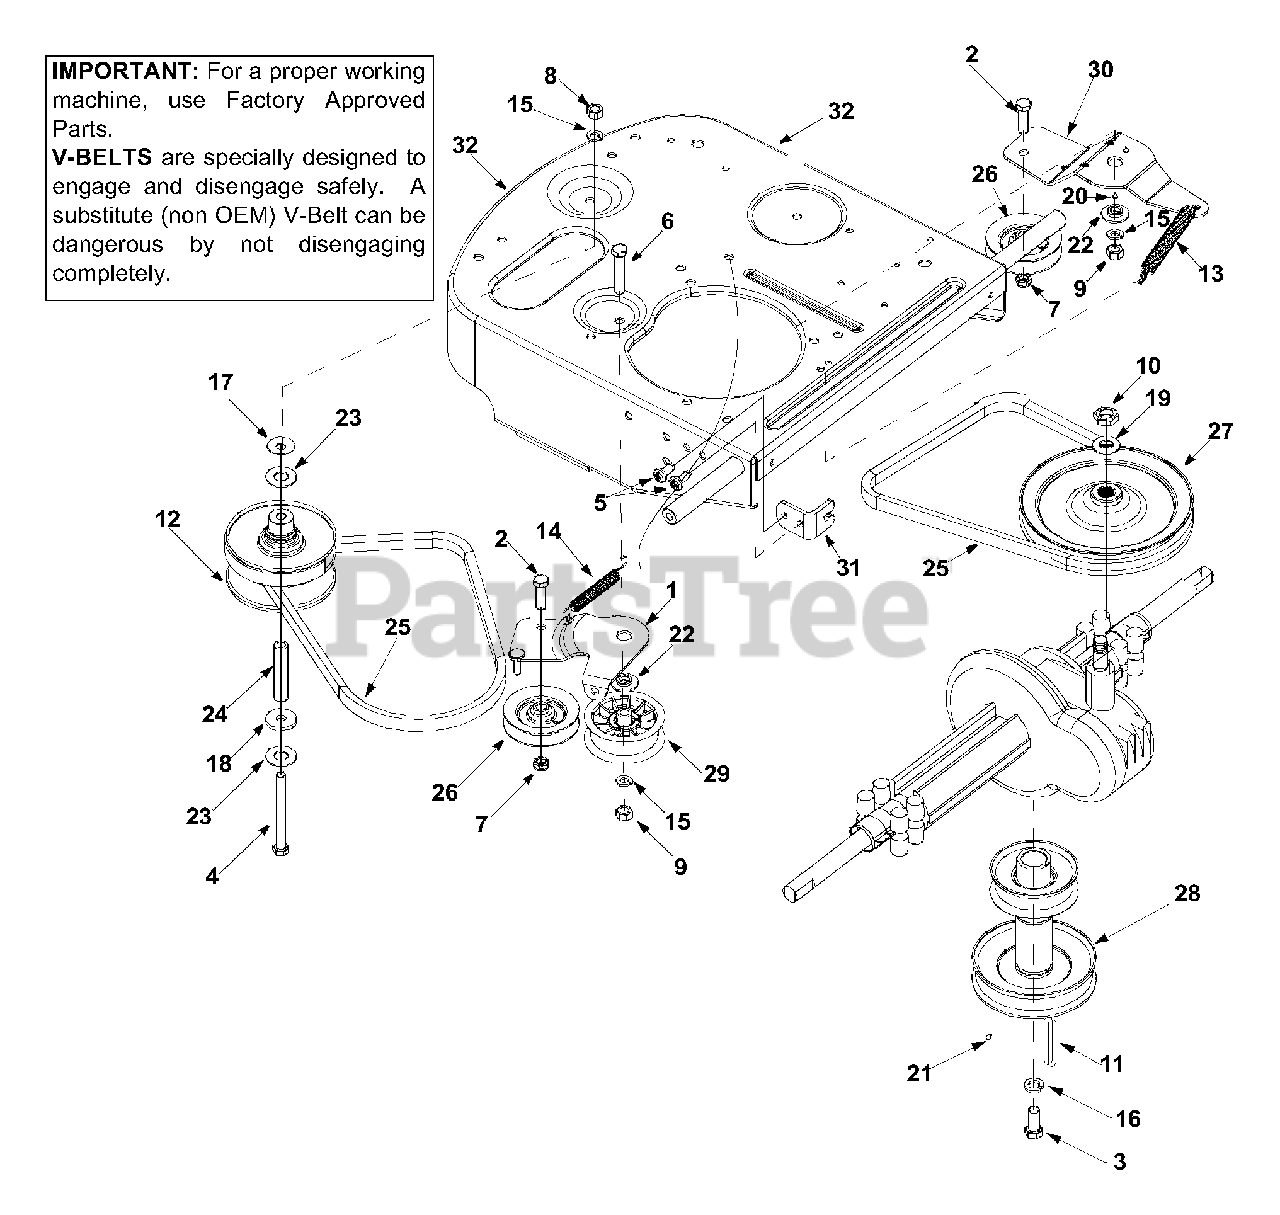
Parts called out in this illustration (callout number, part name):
1	Idler Bracket Assembly
2	Hex Screw (Special)
3	Hex Screw 7/16-20 x 1.0"
4	Hex Screw 3/8-24 x 3.75"
6	Hex Screw 3/8-16 x 2.0"
7	Jam Lock Nut
8	Hex Nut 3/8-24
9	Hex Nut 3/8-16
10	Jam Nut 9/16-18
11	Sq. Key
12	Variable Speed Pulley Assembly
13	Extension Spring
14	Extension Spring
15	Lock Washer
16	Lock Washer
17	Bell Washer
18	Flat Washer
19	Beleville Washer
22	Shoulder Spacer
23	Thrust Bearing
24	Slv. Spacer
25	V-Belt
26	Idler Pulley
27	Transmission Pulley
28	Engine Pulley
29	Flat Idler Pulley
30	Idler Bracket: Variable Speed
31	Cable Bracket
